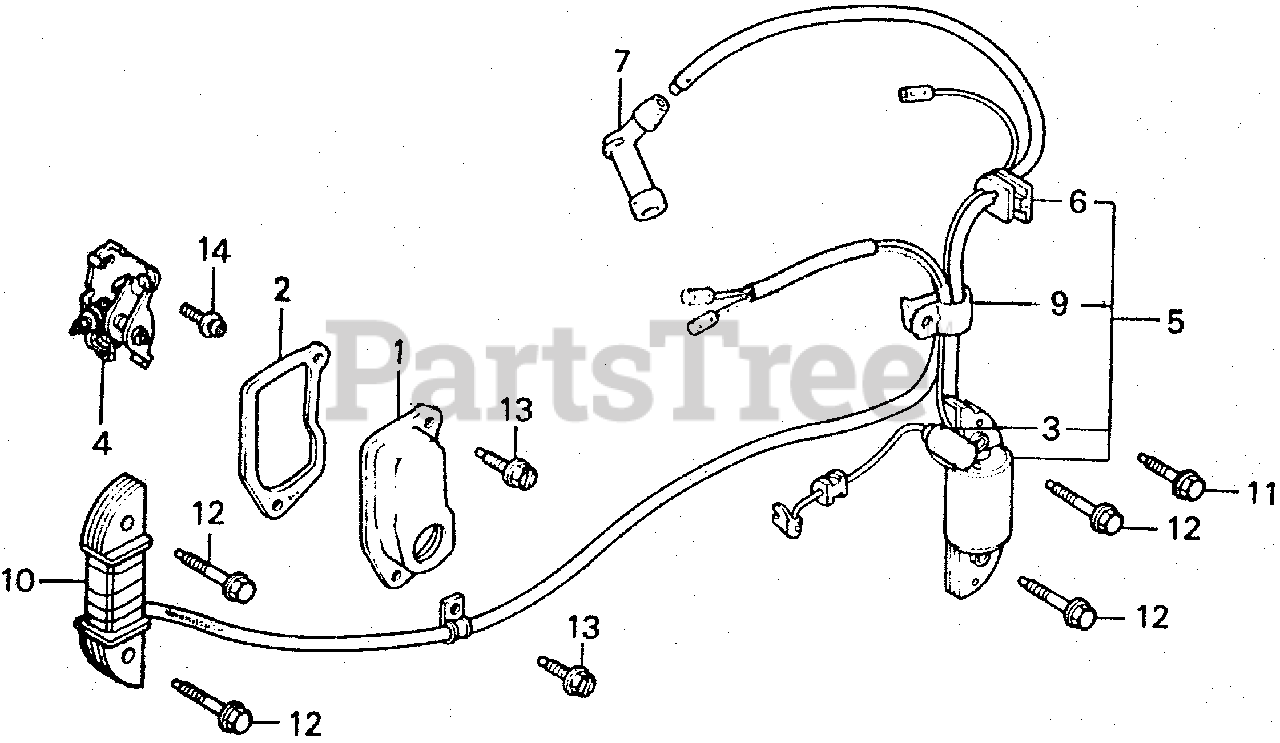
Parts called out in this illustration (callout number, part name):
1	COVER, BREATHER
2	GASKET, COVER
3	CONDENSER
4	POINTS ASSY.
5	COIL ASSY., IGNITION
6	GROMMET, WIRE
7	CAP ASSY., NOISE SUPPRESSOR
9	CLAMP, IGNITION WIRE
10	COIL ASSY., CHARGE (SILICON RECTIFIER)
11	BOLT, FLANGE (6X12) (CT200)
12	BOLT, FLANGE (6X32)
13	BOLT, FLANGE (5X10)
14	SCREW-WASHER (5X12)
